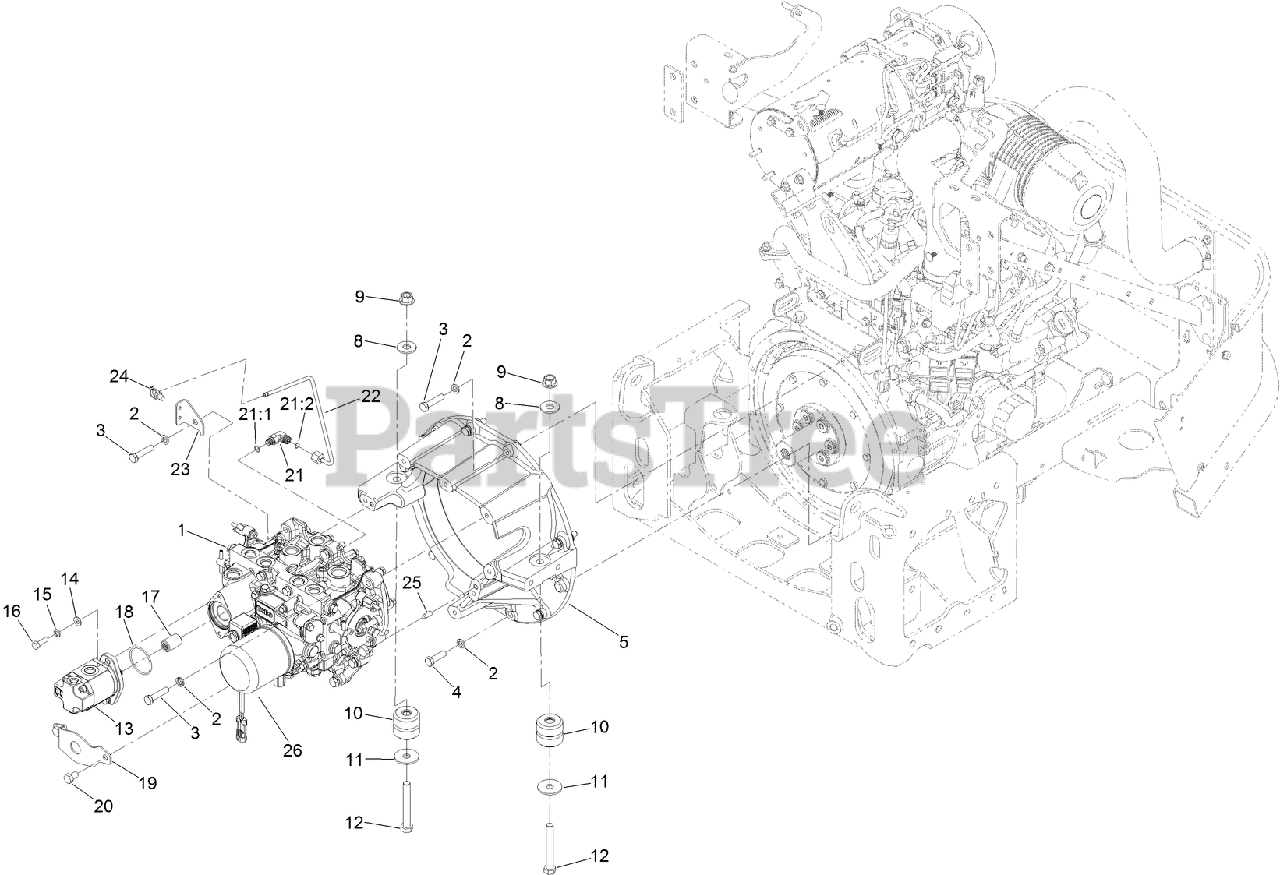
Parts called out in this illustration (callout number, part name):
1	TRANSMISSON ASM
2	WASHER-LOCK
3	SCREW-HH
4	SCREW-HH
5	HOUSING-FLYWHEEL
8	WASHER-FLAT
9	NUT-LOCK
10	MOUNT-ISOLATOR
11	WASHER-THRUST
12	SCREW-HH
13	HYD GEAR PUMP ASM
14	WASHER-PLAIN
15	SCREW-HH
16	SCREW-HH
17	COUPLER-SPLINE
18	O-RING
19	SHIELD-SEAL
20	SCREW-HH
21	FITTING-ELBOW, 90 DEG
21:1	O-RING
21:2	O-RING
22	TUBE ASM
23	SUPPORT-TUBE
24	CLIP-TIE
25	PIN-DOWEL
26	FILTER-OIL, HYD
